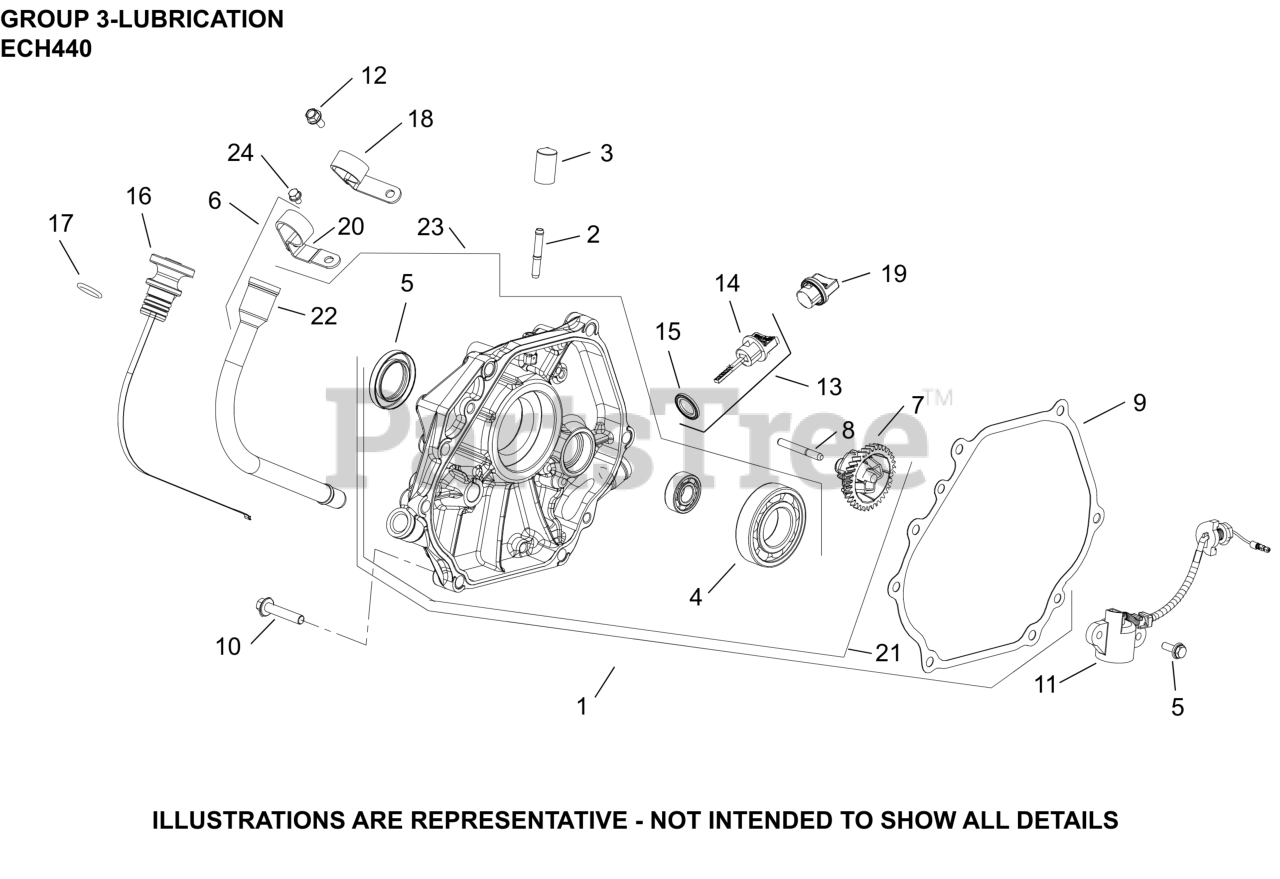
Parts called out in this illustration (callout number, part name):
6	ASSEMBLY, TUBE DIPSTICK & BRACKET
9	GASKET, CLOSURE PLATE
10	SCREW, CLOSURE PLATE
11	SWITCH, OIL SENSOR ASSEMBLY
12	SCREW, HEX FLANGE (M6)-USE 25 086 433-S
16	DIPSTICK, ASSEMBLY
17	O-RING, DIPSTICK CAP
20	BRACKET, DIPSTICK TUBE
22	TUBE, DIPSTICK
23	PLATE, CLOSURE & BEARING
24	SCREW, M5 X 8
NI	PLUG, PIPE (W/SEALANT)
